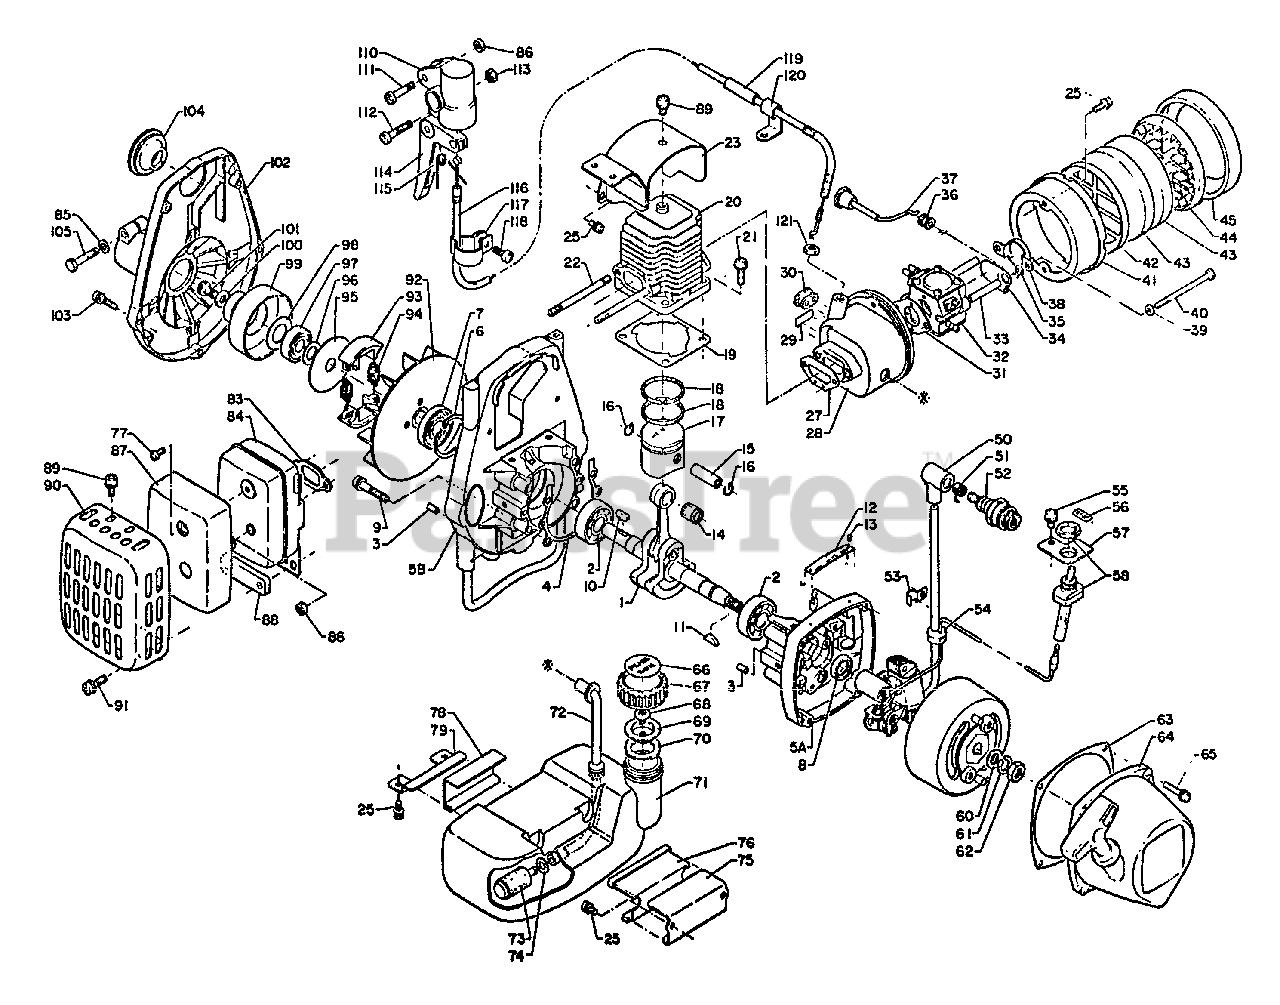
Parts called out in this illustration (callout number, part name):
1	CRANKSHAFT ASSY
2	BEARING, BALL - 6201 C3
3	PIN, LOCATING 4
4	GASKET, CRANKCASE
5	CRANKCASE KIT
5A	CRANKCASE KIT
5B	CRANKCASE KIT
6	RING, SNAP Ø32
7	SEAL, OIL 12
8	SEAL, OIL
9	SCREW 5×28
12	MODEL PLATE
13	RIVET
14	BEARING, NEEDLE 8
15	PIN, PISTON
16	RING, SNAP
17	PISTON KIT
18	RING, PISTON
19	GASKET, CYLINDER
20	CYLINDER
21	SCREW 5×16
22	STUD
23	SHIELD, CYLINDER
25	SCREW 4×10
27	GASKET, INTAKE
28	CASE, CARBURETOR
29	LABEL - CAUTION
31	GASKET, INTAKE
32	CARBURETOR
33	SPACER
34	SHUTTER, CHOKE
35	WASHER 5.5×8×0.8
36	GROMMET, CHOKE
37	ROD, CHOKE
41	CASE, AIR FILTER
42	RETAINER, AIR FILTER
43	FILTER, AIR
44	COVER, AIR FILTER
45	COVER, AIR FILTER
50	CAP, SPARK PLUG
51	TERMINAL, SPARK PLUG CAP
52	SPARK PLUG - BM6A
53	CLAMP
55	SCREW 5×12
56	LABEL, ON-OFF
57	BRACKET, SWITCH
58	IGNITION SWITCH ASSY
61	WASHER, SPRING 8
62	NUT 8×1.25
63	GASKET, STARTER
64	STARTER ASSY
65	SCREW 4×20
66	LABEL - FUEL MIX
67	CAP
68	VALVE, CHECK
69	HOLDER, CHECK VALVE
70	GASKET, CAP
71	TANK, FUEL
72	PIPE, FUEL
73	FILTER, FUEL
74	WASHER 6.5×11.5×0.8
75	BRACKET, FUEL TANK
76	CUSHION, FUEL TANK
78	CUSHION, FUEL TANK
79	BRACKET, FUEL TANK
83	GASKET, MUFFLER
84	MUFFLER
85	WASHER, FLAT 5.5×10×0.8
86	LOCKNUT - 5
87	INSULATOR
88	SPACER
89	SCREW 5×10
90	COVER, MUFFLER
91	SCREW 5×16
92	FAN
93	SHOE, CLUTCH
94	SPRING, CLUTCH
95	PLATE, CLUTCH
96	WASHER, CLUTCH
97	BEARING, BALL 6000
99	DRUM, CLUTCH
100	WASHER 6
101	BOLT M6×10
102	CASE, FAN
103	SCREW 4×18
104	COVER, SPARK PLUG
105	BOLT - 5×25
110	BRACKET, TRIGGER
112	SCREW 5×28
113	NUT M5
114	TRIGGER, THROTTLE
116	CABLE, THROTTLE
118	SCREW 5×10
119	TUBE, VINYL
120	CLAMP
